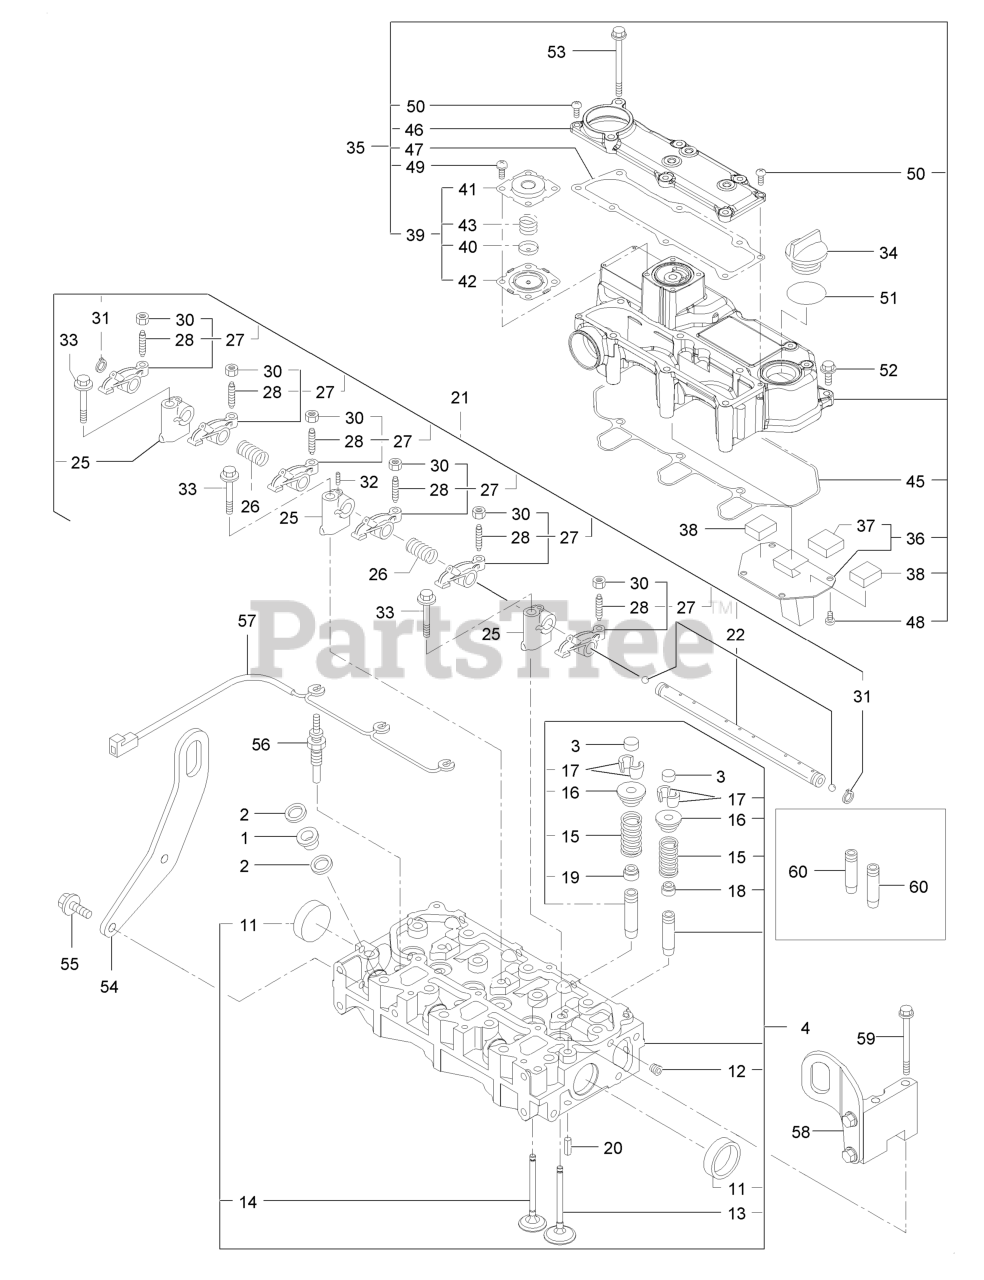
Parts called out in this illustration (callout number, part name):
1	Protector-Nozzle
2	Gasket-Nozzle
3	Cap-Valve
4	Head ASM-Cylinder
11	Plug-Cup
13	Valve-Suction
14	Valve, Exhaust 3
15	Spring-Valve
16	Retainer
18	Seal-Stem, Valve
19	Seal-Stem, Valve
20	Pin-Spring
21	Support ASM-Rocker
22	Shaft ASM-Rocker
25	Support-Rocker Arm
26	Spring-Rocker
27	Arm ASM-Rocker
28	Screw-Adjust, Valve
34	Cover-Filler
35	Bonnet ASM
36	Plate-Baffle
37	Baffle-Breather
38	Baffle-Breather
39	Diaphragm ASM
40	Plate-Diaphragm
41	Cover-Diaphragm
42	Diaphragm
43	Spring-Diaphragm
45	Gasket-Bonnet
46	Cover ASM-Bonnet
54	Lifter-Engine
56	Plug-Glow
57	Connector-Glow Plug
58	Lifter ASM
